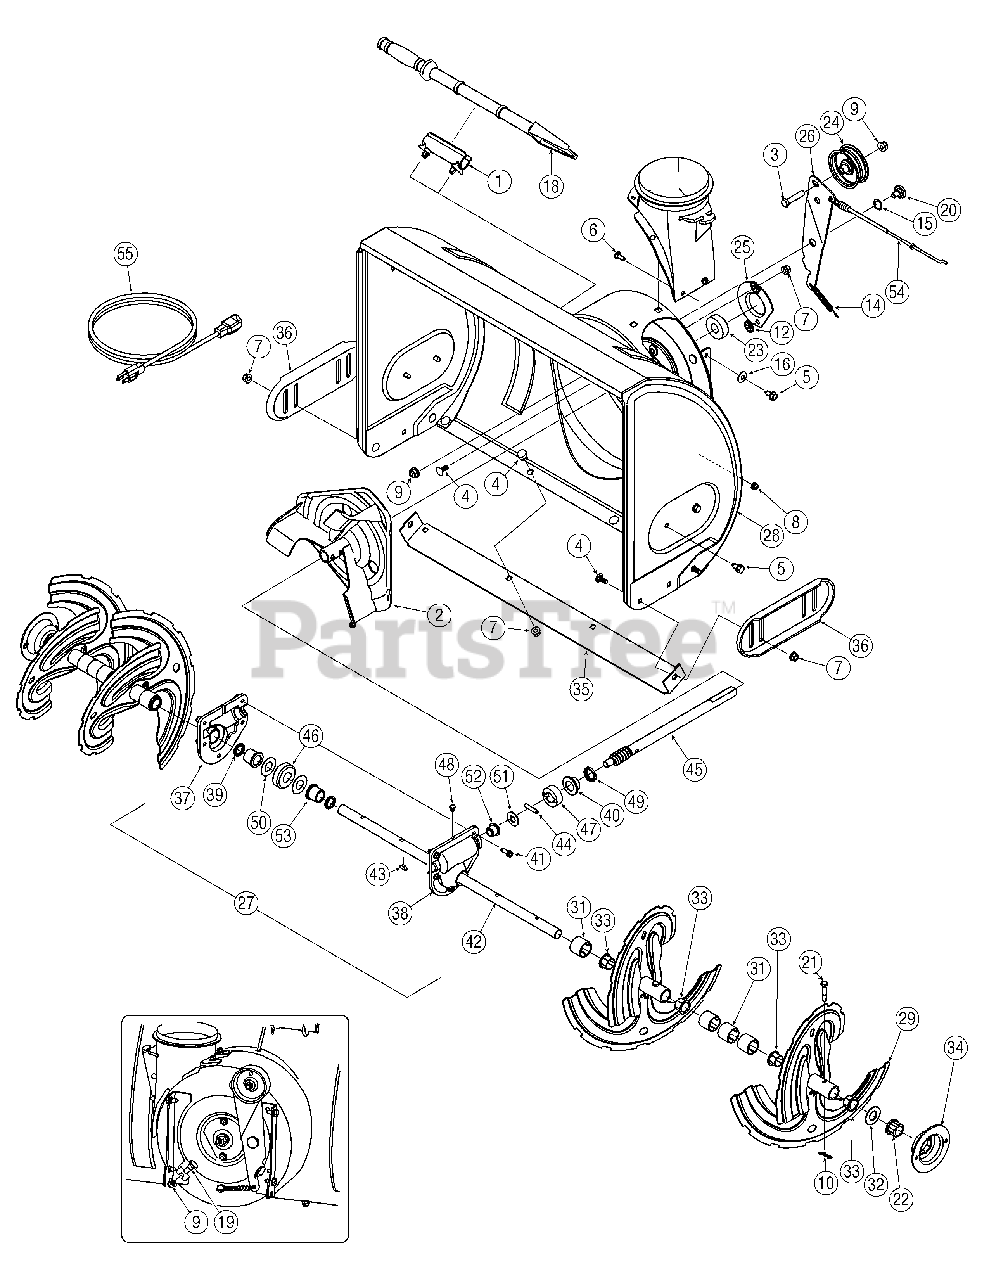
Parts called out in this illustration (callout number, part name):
1	Snow Removal Tool Mount
3	Hex Screw, 3/8-16, 1.75, Gr5
4	Bolt, Carriage, 5/16-18, .750
5	Screw, 5/16-18, 0.625
6	Screw, Carriage, 1/4-20, .750, Gr 5
7	Nut, Flange Lock, 5/16-18, Nylon
8	Nut, Flange Lock, 1/4-20, Nylon
9	Nut, Flange Lock, 3/8-16, Nylon
10	Cotter Pin, Bow-tie
11	Cable, Tie, 3/16 x .05 x7.4
12	Nut, Push-on, .25 Dia
13	Chute, Adapter 5" Dia
14	Spring, Extension, .38 OD x 3.6
15	Washer, Wave, .625 x .885
16	Washer, Bell, .340 x .872
17	Washer, Flat, .25 x .630 x .0515
18	Snow Removal Tool
19	Screw, Shoulder, .498 x .34, 3/8-16
20	Screw, Shoulder, .625 x .17, 3/8-16
21	Shear Pin, .25 x 1.50
22	Bearing, Hex Flange x .75
23	Bearing, Ball, .75 ID x 1.85 OD
24	Flat Pulley, Idler, 2.75 OD
25	Housing, Bearing, 1.85 ID
27	Gearbox Assembly, Auger, 26"
27	Gearbox Assembly, Auger, 28"
31	Spacer, 1.25 OD x .75 ID x1.00 - See footnote
32	Washer, Flat, .76 x 1.49 x .06
33	Bushing, Flange, .80 ID x .91 OD
37	Housing, Auger, RH Reduced
38	Housing, Auger, LH Reduced
39	Seal, Oil, .750 ID
40	Bearing, Flange, .75 x 1.0
41	Screw, Self-tapping, 1/4-20, 0
42	Axle, Auger, 26"
42	Axle, Auger, 28"
43	Key, Hi-pro 3/16 x 5/8
44	Pin, Dowel, .25 OD x 1.2
45	Shaft, Worm .75 OD
46	Gear, Worm 20T
47	Collar, Thrust
48	Plug, 1/4 x .437
49	Seal, Oil, .75 x 1 x .131
50	Washer, Flat, .760 ID x 1.5 OD
51	Washer, Flat, .51 x 1.12
52	Bearing, Flange, .75 x 1.0 x .925
53	Bearing, Flange, .75 x 1.00 x .975
54	Clutch Cable, Auger, 47.23"
55	Extension Cord, 110V
